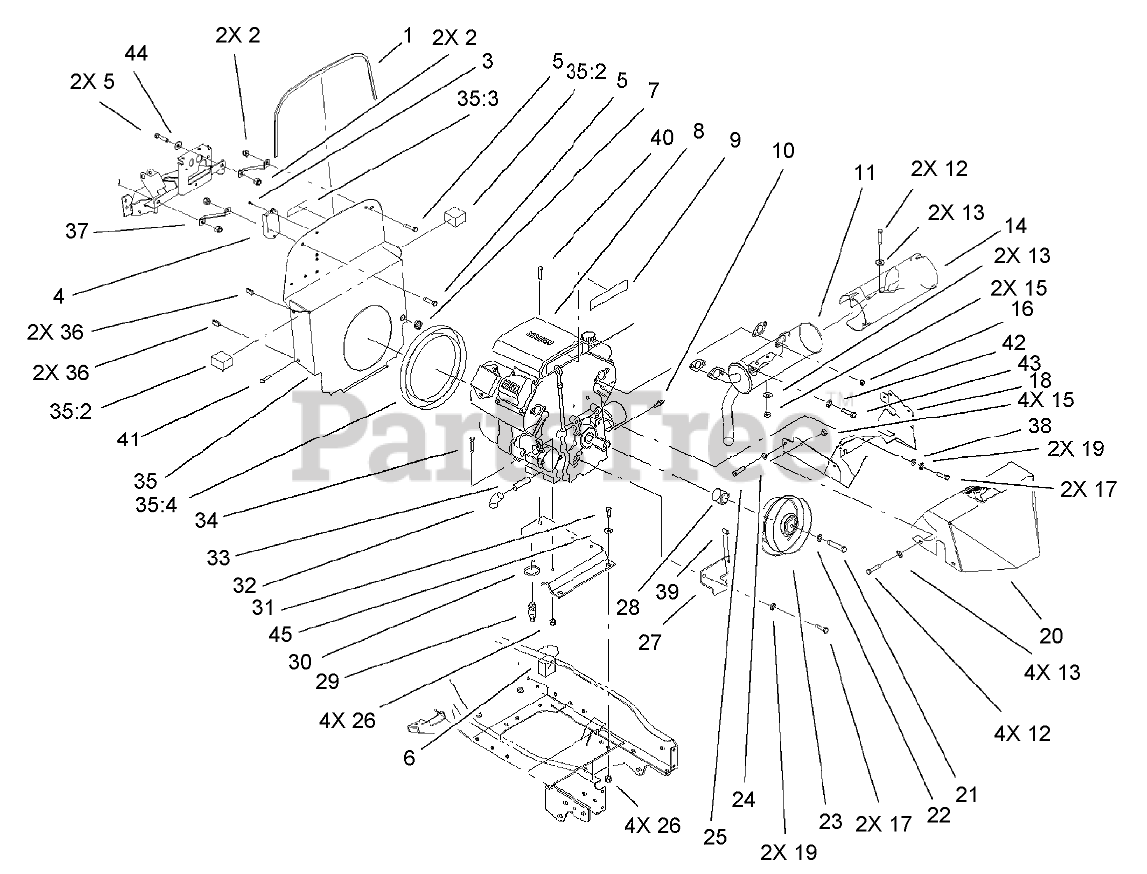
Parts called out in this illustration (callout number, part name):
1	TRIM-LOCK
2	NUT-LOCK, NI
3	SCREW-HWH
4	MODULE-LOW VOLTAGE
5	SCREW-HH
6	SEAL-FOAM, SIDE
7	GROMMET
10	SENDER-OIL TEMPERATURE
11	MUFFLER
12	SCREW-HH
13	WASHER-FLAT
14	REFLECTOR - HEAT
15	NUT-LOCK, CONE
16	NUT-HF
17	SCREW-HH
18	SHROUD-MUFFLER
19	WASHER-LOCK
20	SHROUD-MUFFLER
21	SCREW-HH
22	WASHER-FLAT
23	CLUTCH-PTO
24	WASHER-LOCK
25	SCREW-HH
26	NUT-LOCK, NI
27	CLUTCH-STOP
28	SPACER-CLUTCH
29	VALVE-DRAIN, OIL
30	PLATE-ENGINE
31	SCREW-HH
32	ELBOW-90 DEGEE
33	NIPPLE
34	SCREW-HH
35	BULKHEAD / DECAL ASM
35:2	SEAL-FOAM, SIDE
35:3	DECAL-WARNING
35:4	SEAL-FOAM
37	BRACKET-BULKHEAD
38	WASHER-FLAT
39	BUMPER
40	SCREW-TAPTITE
41	SCREW-HH
42	WASHER-LOCK
43	SCREW-HHF
44	WASHER-PLAIN
45	WASHER-FLAT
